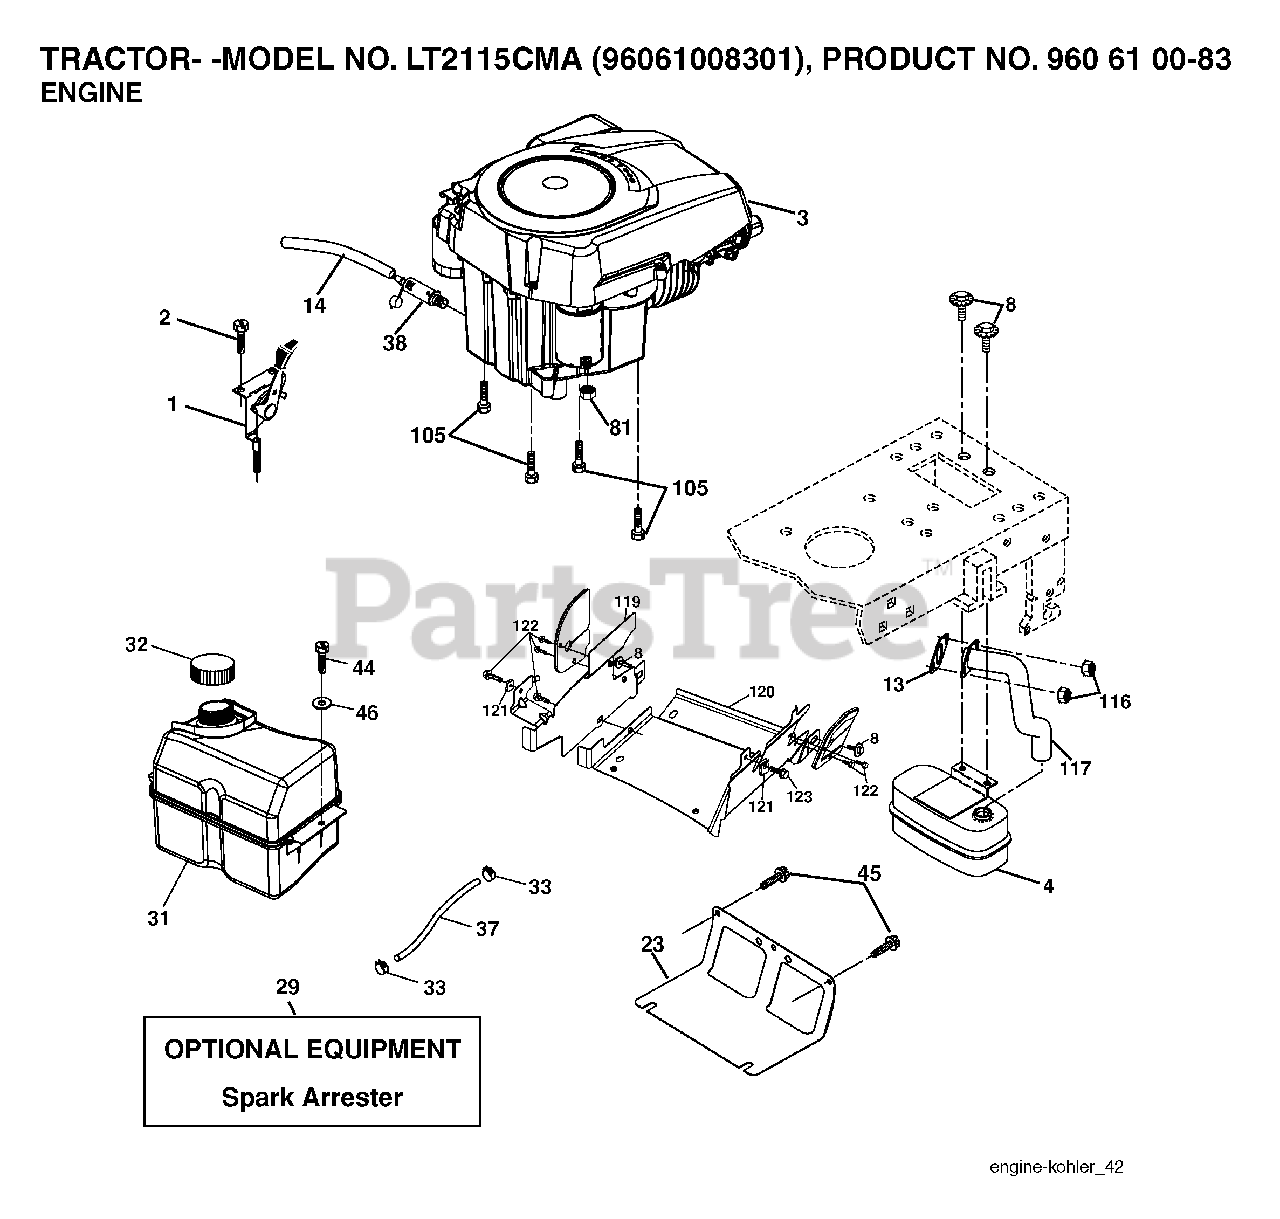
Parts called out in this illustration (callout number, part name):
1	CONTROL.THROTTLE.LT/YT
2	SCREW
4	MUFFLER.SINGLE.CYL.KOHL/B&S
8	BOLT, 5/16-18 X 1 3/4
13	GASKET ENGINE
14	TUBE, DRAIN OIL ASM.
23	SHEILD.BROWNING.DBR.GUARD
29	ARRESTER SPARK (OPTIONAL)
31	TANK FUEL
32	FUEL CAP
33	HOSE CLAMP
37	LINE.FUEL.20
38	PLUG DRAIN OIL EASY
44	SCREW HEXWSHR 1/4-20X3/4
45	SCREW, 3/8-16X3/4
81	NUT
105	SCREW 3/8-16X1
116	NUT.HEX.FLANGE.TOPLOCK
117	TUBE EXHAUST
122	SCREW.1/4-20X5/8
123	SCREW, 5/16-18 X 1/2
